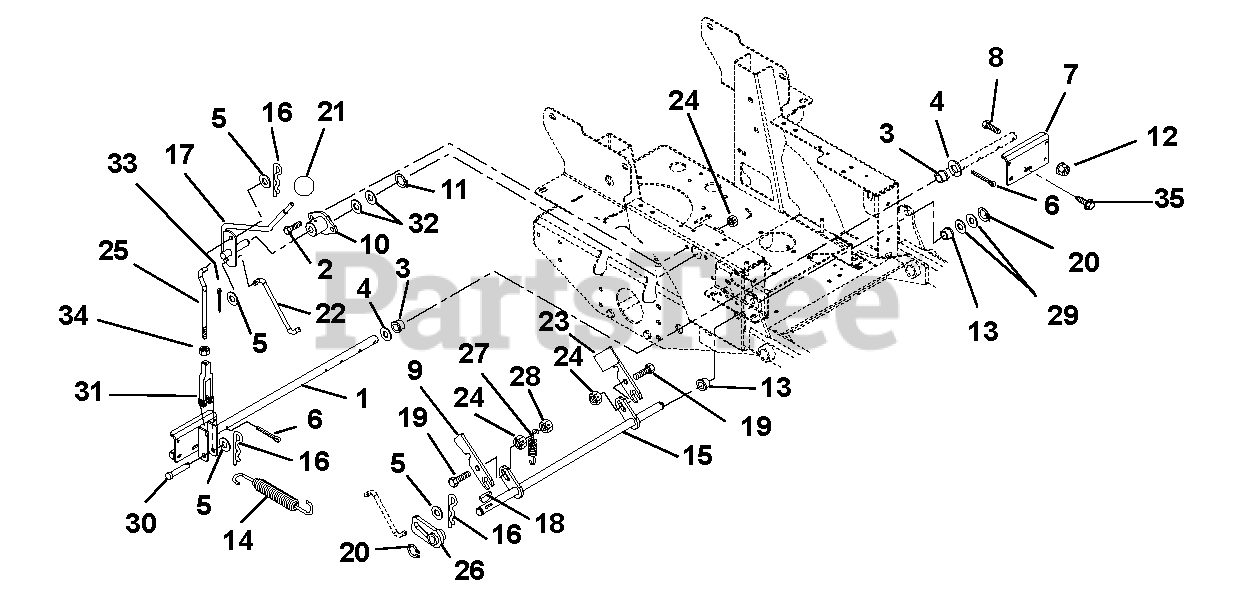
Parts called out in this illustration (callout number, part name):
1	Weldment, Brake Shaft
2	Bolt, Hex .31-18 x 1.00
3	Bushing, Flange .762 x 1.00 x .58 x 1.48 Nylon
4	Washer, Flat Steel .755 x 1.375 x .062
5	Washer, Flat Steel .406 x .812 x .065
6	Pin, Cotter .12 x 1.00 Extended Prong Square Cut
7	Paddle, Brake
8	Bolt, Hex .25-20 x 1.5
9	Slide, Interlocking Brake
10	Bushing, Flange
11	Ring, Retaining External .625 x .05
12	Nut, Nyloc Flange .25-20
13	Bushing, Flange .515 x .75 x .745 x 1.00
14	Spring, Engine Transmission
15	Weldment, Mechanical Brake
16	Pin, Hair
17	Weldment, Brake Actuating
18	Key, Woodruff .13 x .63
19	Bolt, Round Head Square Neck .31-18 x 1.25
20	Ring, Retaining External .50 x .05
21	Knob, Steering Lock
22	Linkage, Brake Actuating
23	Interlock, Safety Switch
24	Nut, Nyloc Flange 5/16-18
25	Linkage, Brake Compact-Z
26	Weldment, Parking Brake Hub
27	Spring, Tension .061 x .50 x 3.0
28	Nut, Locking Center .31-18
29	Washer, Flat Steel .505 x 1.00 x .062
30	Pin, Clevis .37 x 1.75
31	Clevis, .38-24 Adjustable Swivel
32	Washer, Flat Steel .630 x 1.250 x .062
33	Pin, Cotter .09 x .75 Extended Prong Square Cut
34	Nut, Jam .375-24
35	Screw, Tapping .31-18 x .75 Hex Washer Head Thread Rolling
